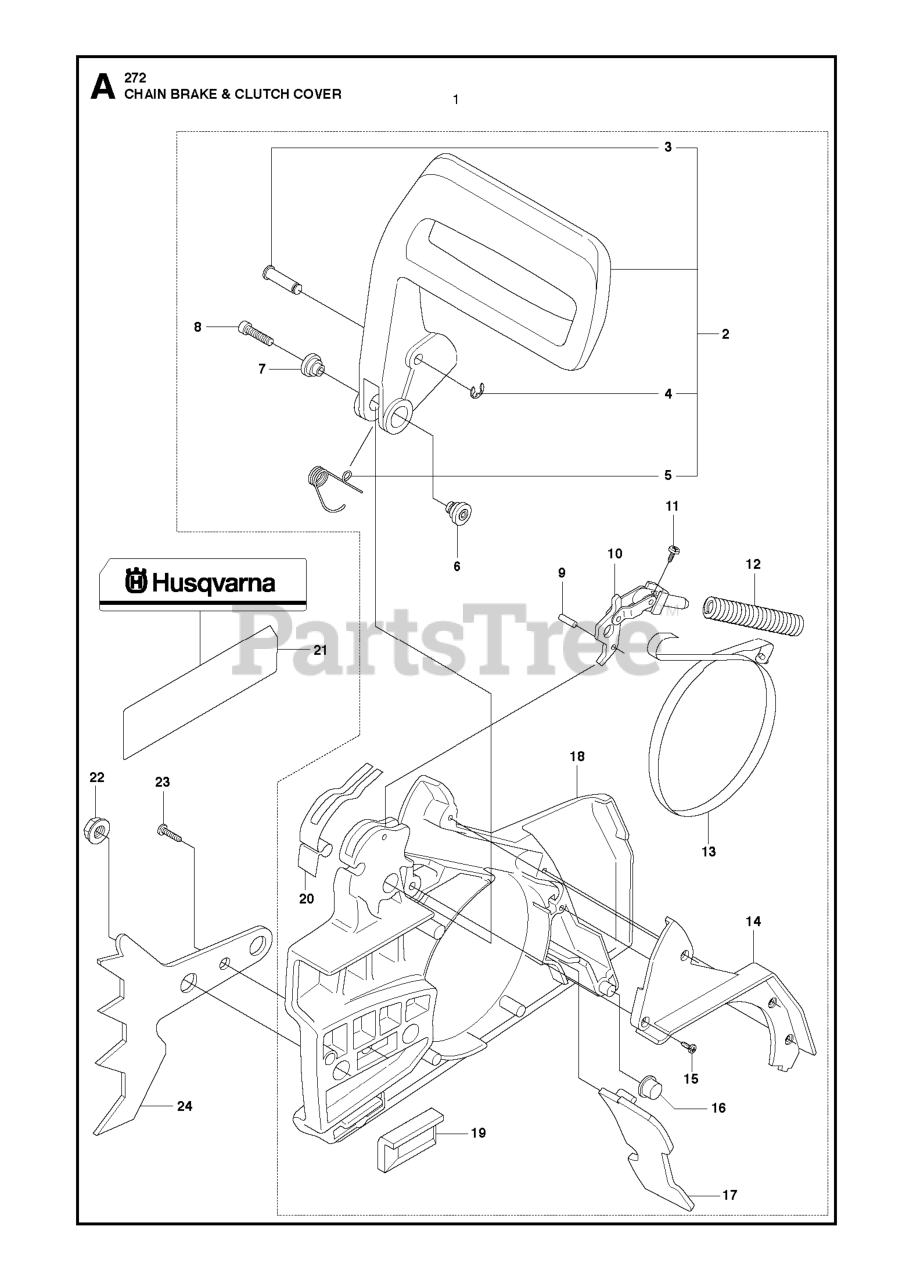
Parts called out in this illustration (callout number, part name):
1	CHAIN BRAKE
6	PIVOT SLEEVE L
7	PIVOT SLEEVE R
9	HARDENED PIN
12	BRAKE SPRING
13	BRAKE BAND
18	CLUTCH COVER
19	CHAIN GUIDE
22	NUT M8 FLANGE
23	SCREW MC6S 5X12
24	FELLING DOG
